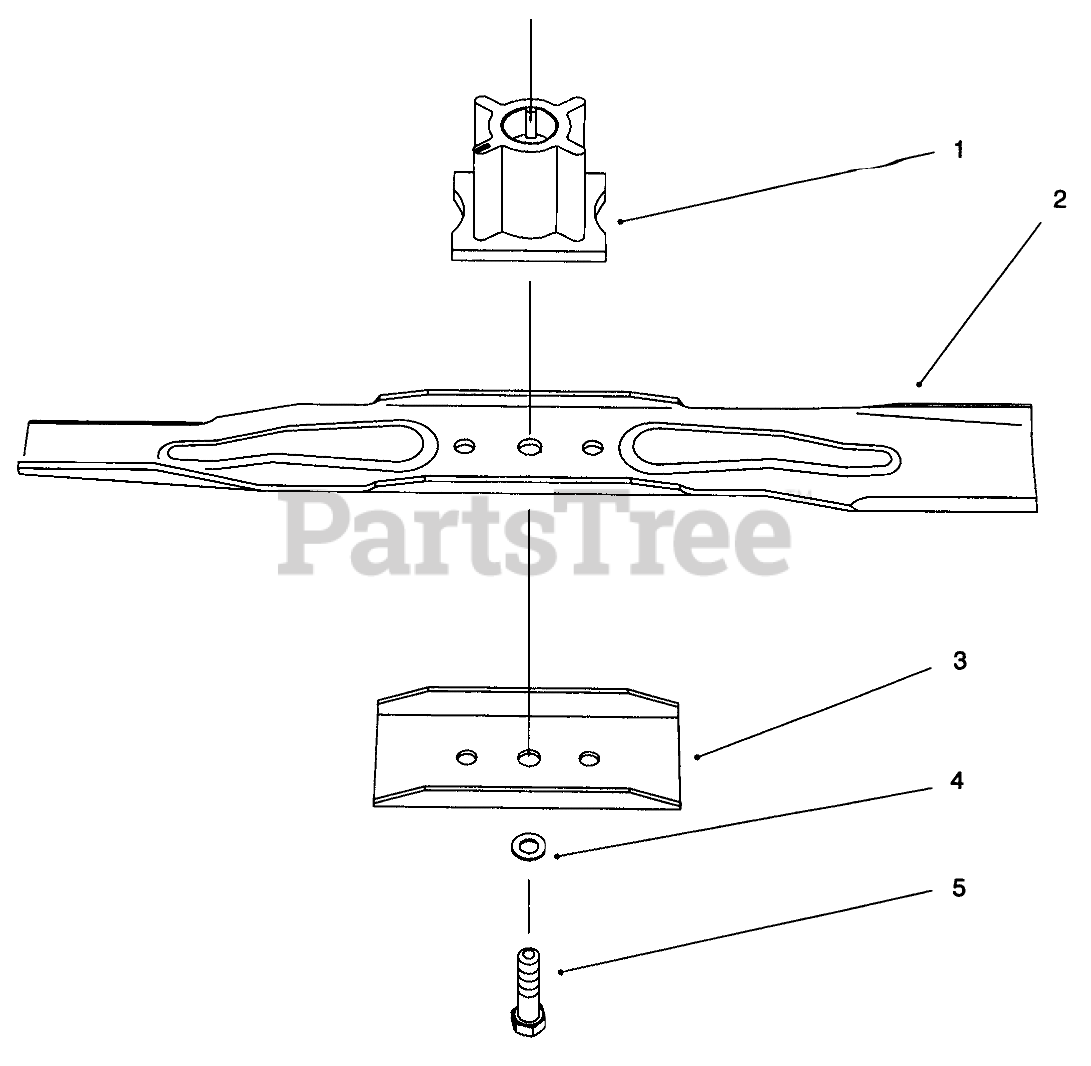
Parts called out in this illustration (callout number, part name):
1	BLADE RETAINER - 25 MM
2	Blade
3	Stiffener Blade
4	WASHER-LOCK
5	BOLT-BLADE
